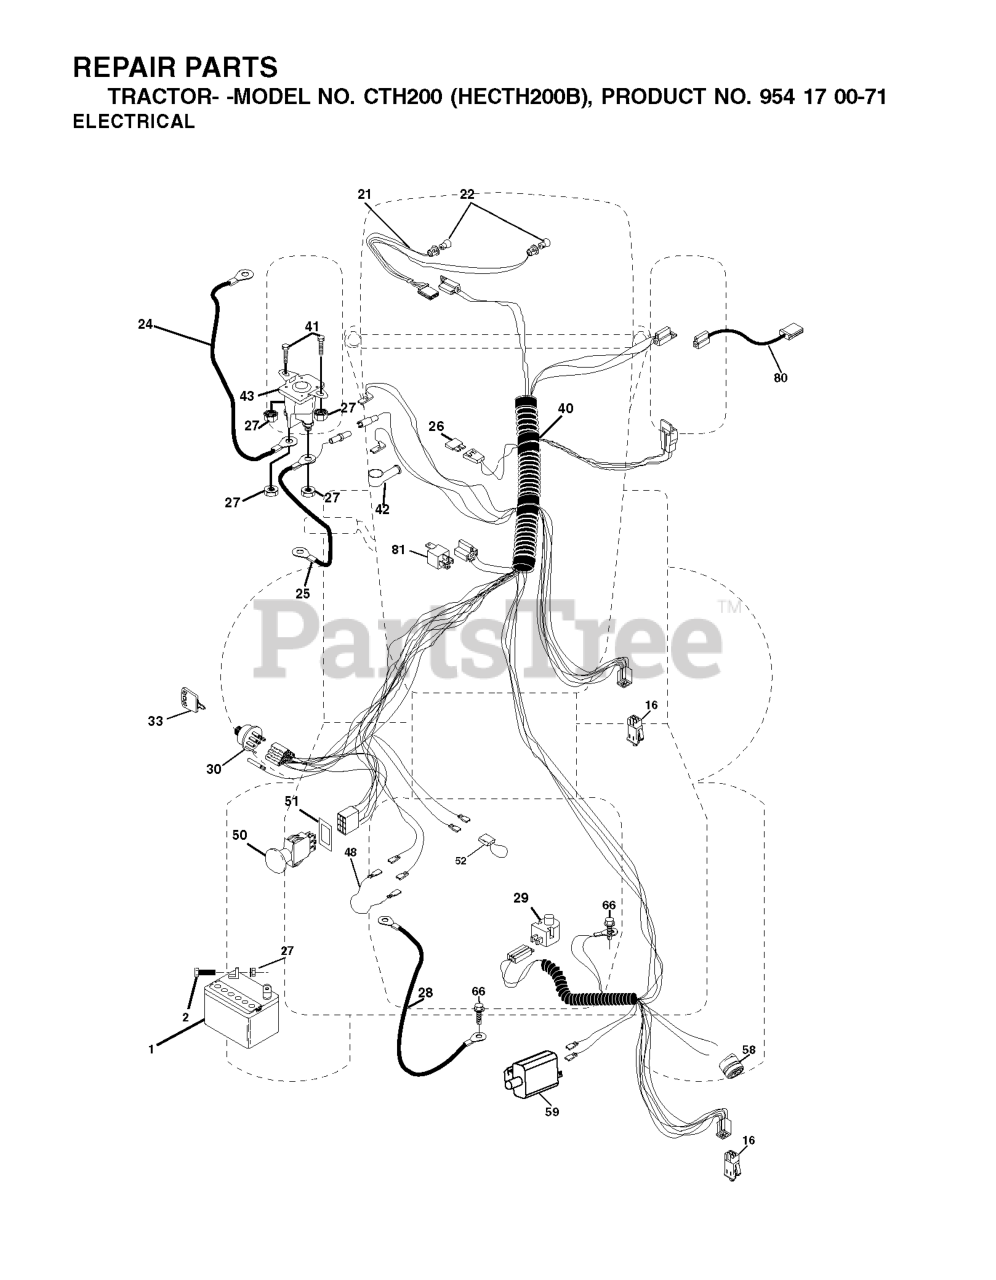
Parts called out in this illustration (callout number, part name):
1	BATTERY 12V .35 AMP
2	BOLT.HEX.1/4.X.3/4.DICHROMATE
16	SWITCH INTERLOOK PUSH-IN
24	BATTERY CABLE GT
25	CABLE BATTERY
26	FUSE 20AMP
27	NUT
28	CABLE GROUND
29	PLUNGER SWITCH (COLOR:OLIVE)
30	IGNITION SWITCH
33	KEY MLD GEN DELTA
41	BOLT
42	TERMINAL COVER
43	SOLENOID
48	ADAPTER.AMMETER
50	RP.PTO.SWITCH.8 TERMINAL.BLACK
51	FRAME RETAINING RING
52	WIRE PROTECTION LOOP
58	BUZZER
59	.WITCH.FULL BAGGER.INDICATOR
81	RELAY.ASSY.T
